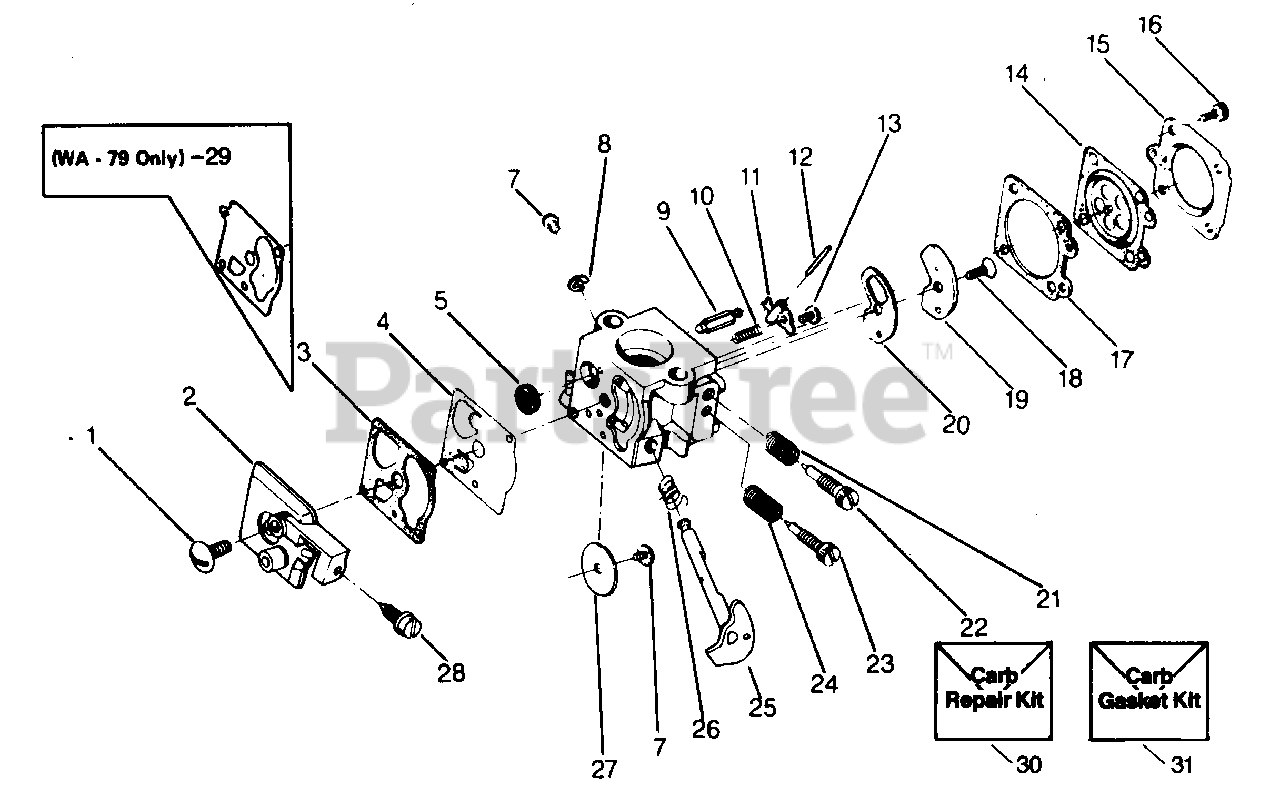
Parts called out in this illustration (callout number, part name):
1	Screw - Pump Cover
2	WA-149 (#35183)
3	Gasket - Pump
3	WA-149 (#35183)
4	Diaphragm - Pump
4	WA-149 (#35183)
5	Screen-Inlet
7	Screw - Throttle Shaft
8	Clip - Throttle Shaft
9	Valve - Inlet Needle
10	Spring - Metering Lever
11	Lever - Metering
12	Pin - Metering Lever
13	Screw - Metering Lever Pin
14	Diaphragm Assembly - Metering
15	Cover - Metering Diaphragm
16	Screw Assembly - Metering Cover & Throttle Shaft Clip
17	Gasket - Metering Diaphragm
18	Screw - Circuit Plate
19	Plate - Circuit
20	Gasket - Circuit Plate
21	Spring - Hi Speed Needle
22	Needle - Hi Speed
23	Needle - Idle
24	Spring - Idle Needle
25	Shaft Assembly - Throttle
26	Spring - Throttle Return
27	Valve - Throttle
28	Screw - Idle Adjustment
29	Diaphragm - Pump (WA-79 only)
30	Kit - Carb. Kwik Repair
30	WA-149 (#35183)
30	WA-79
